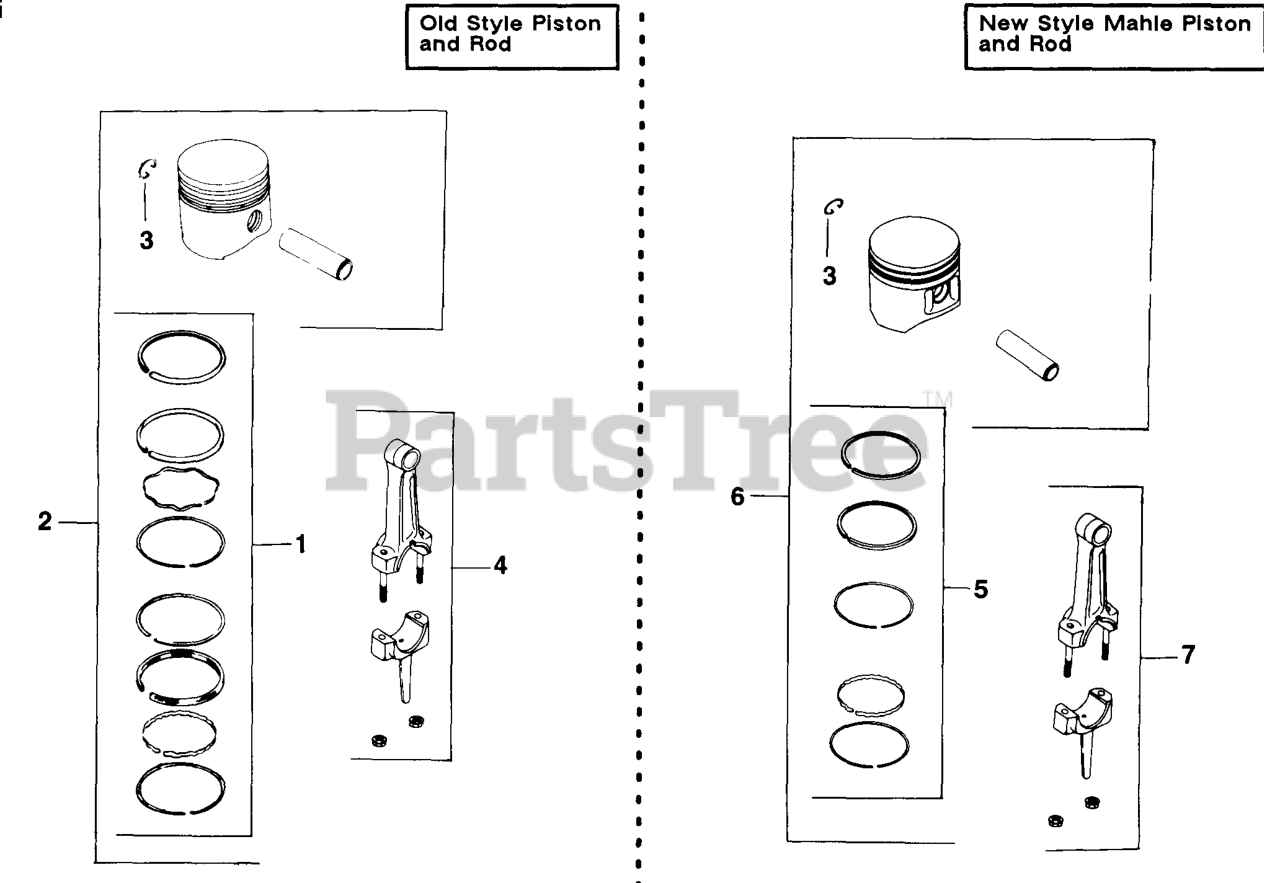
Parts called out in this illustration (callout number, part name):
1	RINGS STD.
1	RINGS .010
1	RINGS .020
1	RINGS .030
2	PISTON W/RING SET STD
2	KIT, PISTON W/RING SET .003
2	KIT, PISTON W/RING SET .010
2	KIT, PISTON W/RING SET .020 - DISCONTINUED
2	KIT, PISTON W/RING SET .030
3	RING, RETAINING
4	ROD STD.
4	ROD .010
5	RINGS STD.
5	RINGS .010
5	RINGS .020
5	RINGS .030
6	KIT, PISTON W/RING SET STD
6	PISTON W/RING SET .003 - DISCONTINUED
6	PISTON W/RING SET .010
6	KIT, PISTON W/RING SET .020 - DISC.
6	PISTON W/RING SET .030
7	ROD STD.
7	ROD .010
